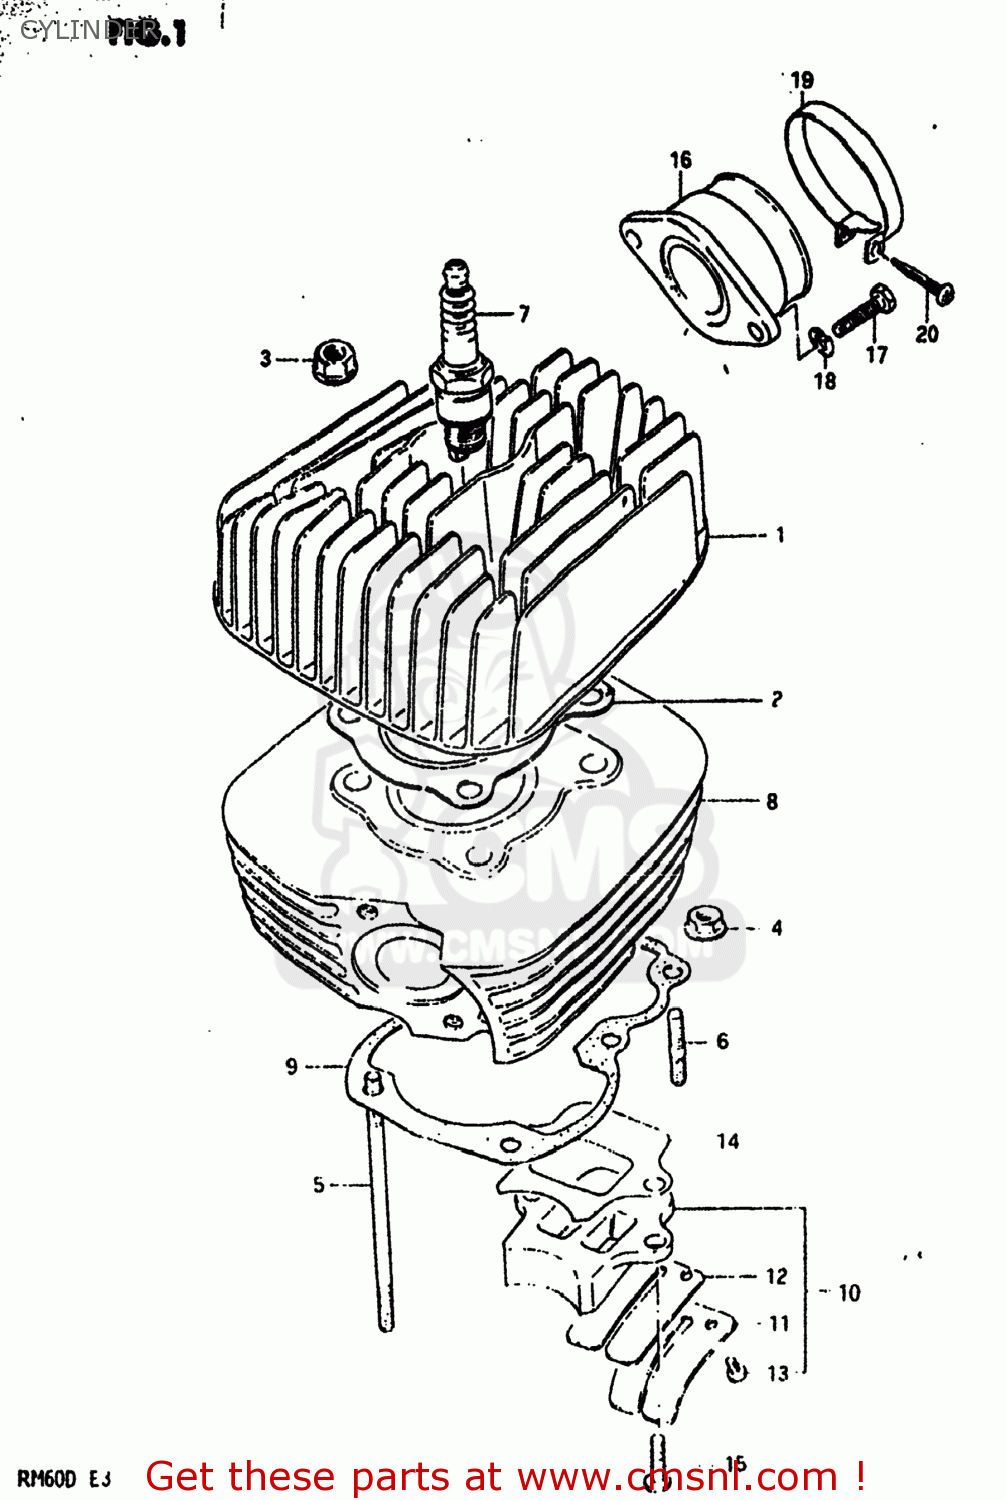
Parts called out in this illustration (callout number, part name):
1	HEAD,CYLINDER
2	GASKET,CYLINDER HEAD (NAS)
3	NUT
4	NUT
5	STUD
6	STUD 6X16
7	PLUG,SPARK(B8HS)
8	CYLINDER
9	GASKET,CYLINDER (MCA)
10	VALVE ASSY,REED
11	STOPPER,REED VALVE
12	VALVE,REED
13	SCREW,REED VALVE
14	GASKET,REED VALVE (MCA)
15	SCREW
16	PIPE,INTAKE
17	BOLT, UPPER
18	LOCK WASHER
19	CLAMP
20	SCREW
